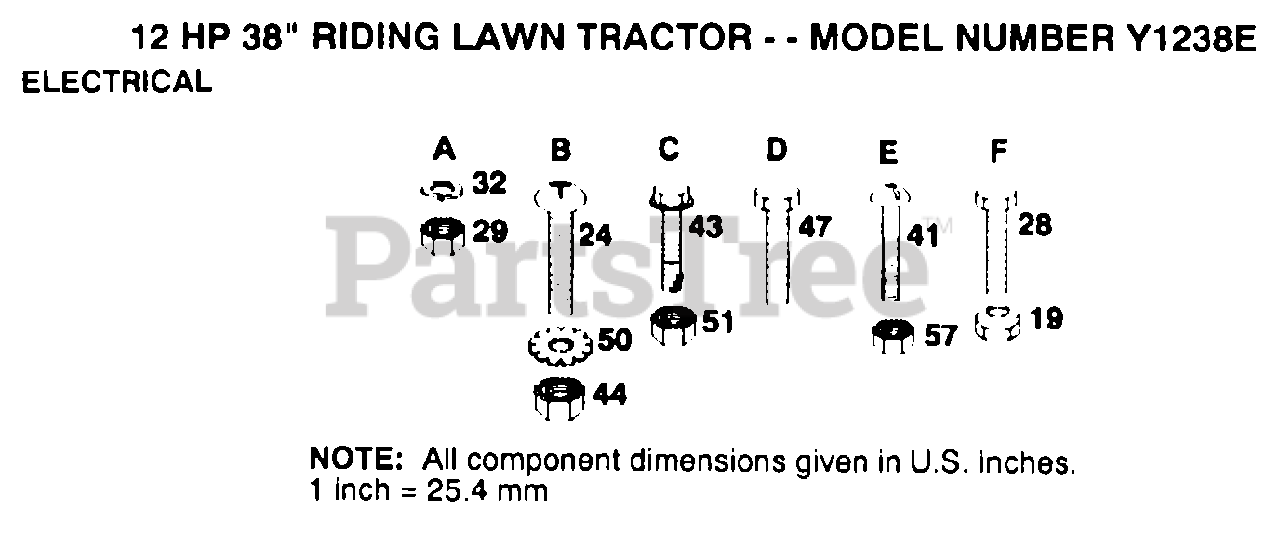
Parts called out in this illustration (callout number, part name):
24	BOLT
28	BOLT
29	NUT
43	SCREW
44	NUT
47	SCREW
51	"NUT,KEPS"
